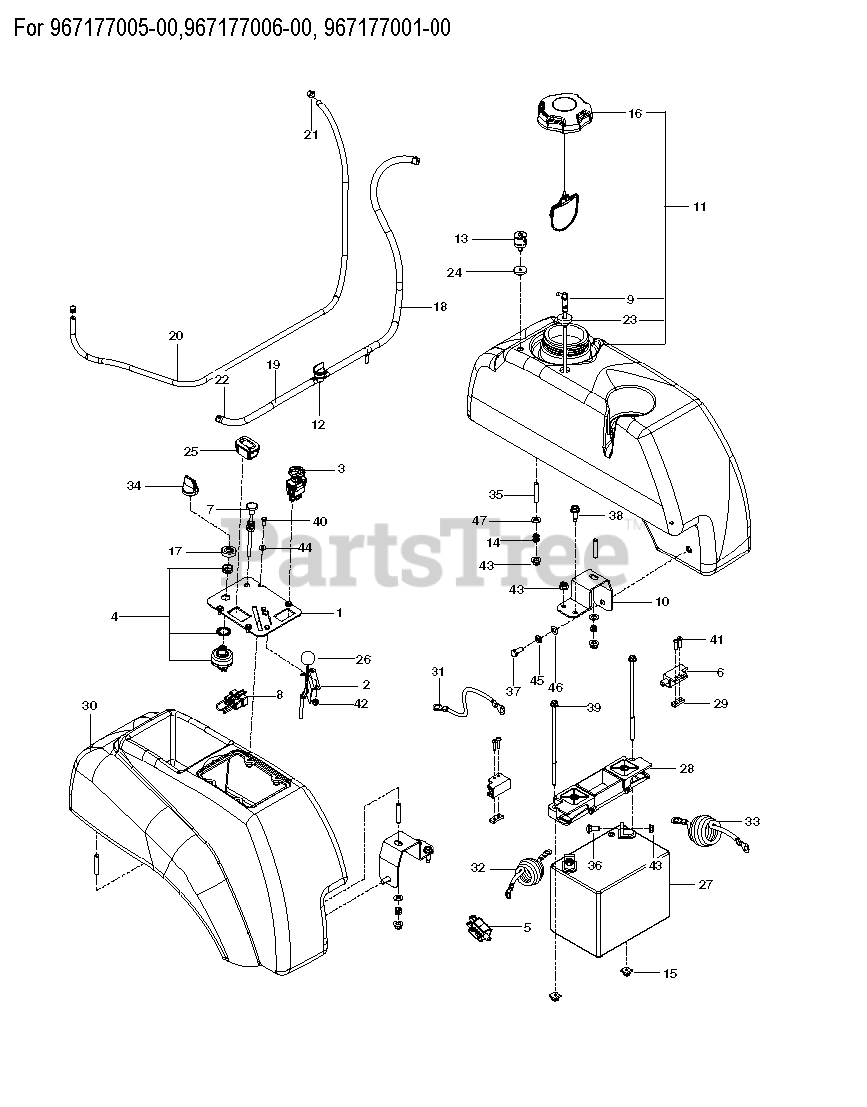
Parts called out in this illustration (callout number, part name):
1	PLATE.CONSOLE.BLACK
2	THROTTLE CONTROL W/BALL KNOB
3	RP SWITCH.PTO.TERMINAL.STD.RED
4	SWITCH, IGNITION, INDAK
5	SWITCH, BRAKE 3P
6	SWITCH INTERLOCKT
7	CABLE, CHOKE
8	PLUG, TIMER
9	FITTING, FUEL
10	SUPPORT, TANK, BLK
11	LT FUEL TANK ASM EPA-BLK
12	FUEL VALVE
13	VALVE.FUEL.CHECK
15	PUSH NUT-NYLON
16	CAP, FUEL
17	CAP IGNITION NUT
18	HOSE, FUEL .25 ID X 26"
19	GAS LINE 10"
20	HOSE, VAPOR 3/16 X 48"
21	CLAMP, HOSE
22	HOSE CLAMP
23	RUBBER GROMMET
24	GROMMET, CHECK VALVE
25	RP.GUAGE.SRVCMNDR.HRMTR.
26	KNOB.ROUND.BALL.BLACK
27	BATTERY, 12 V 330 AMP
28	BATTERY HOLD DOWN
29	TAPPED PLATE
30	FENDER CONSOLE
31	POST.CABLE LONG
32	CABLE POSITIVE
33	NEG. CABLE, 28"
34	KEY, IGNITION
35	STUD, 5/16C
36	BOLT 5/16C X 3/4" CARRIAGE
37	HCS 5/16C X 3/4
38	RP BLT 5/16-18 X 1 THRD FORM D
39	BOLT - 1/4-20 X 7.5
40	HCS #10-24 X 1/2
41	SCR #10-24 X .75 SKT HD BLK
42	NUT 10-24 NYLOC
43	5/16-18 NYLOC FLANGE NUT
44	WASHER #10
45	WASHER.LOCK.HVY.HLCL.SPR.5/16
46	FLAT WASHER 5/16 SAE
